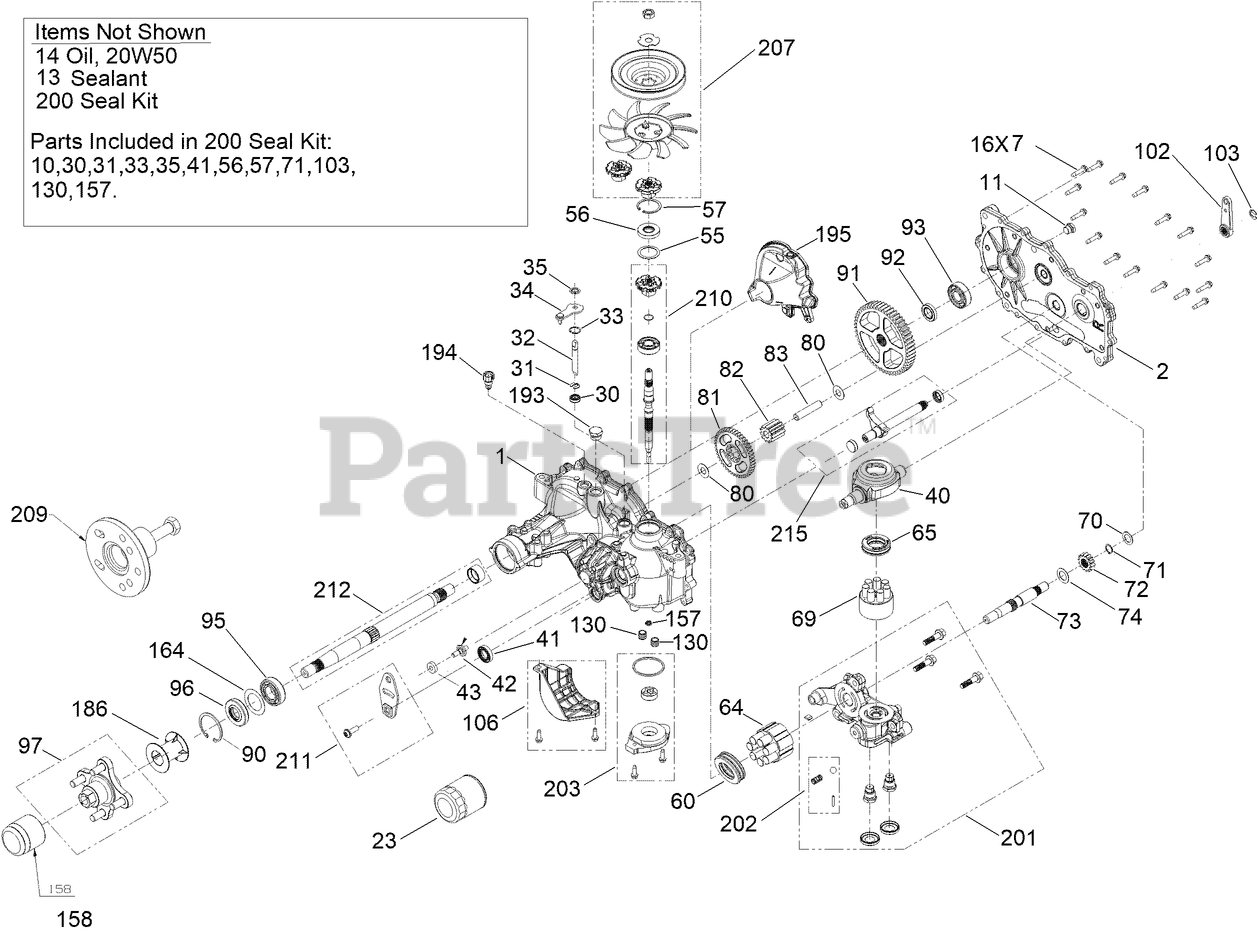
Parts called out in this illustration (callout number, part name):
1	RH MAIN HOUSING KIT
2	RH SIDE COVER KIT
7	SCREW-HHF
13	SEALANT
23	ELEMENT-OIL FILTER, HYD
30	SEAL-LIP
31	RING-RETAINING, EXTERNAL
32	ROD-BYPASS
33	RING-RETAINING, INTERNAL
35	RING-RETAINING, EXTERNAL
40	SWASHPLATE-TRUNNION
41	SEAL-LIP
43	PUCK-FRICTION
55	SPACER
57	RING-RETAINING
60	BEARING-THRUST
64	CYLINDER BLOCK ASM KIT
65	BEARING-THRUST
69	PUMP BLOCK ASM
70	WASHER-FLAT
71	RING-RETAINING
72	GEAR-14T
73	SHAFT-MOTOR
74	WASHER
80	WASHER
81	GEAR-45T
82	GEAR-11T
90	RING-RETAINING
91	GEAR-54T
92	SPACER
93	BEARING-BALL
95	BEARING-BALL
97	HUB-OFFSET
102	HANDLE-BRAKE
103	RING-RETAINING, EXT
106	FILTER GUARD KIT
130	TUBE-CHARGE
157	GEROTOR SEAL KIT
158	CAP-AXLE, LONG
164	SPACER
186	TUBE-AXLE
194	BREATHER FITTING ASM
195	RH INTERNAL EXPANSION TANK ASM
200	SEAL KIT
202	CHARGE RELIEF KIT
203	CHARGE KIT
207	FAN AND PULLEY KIT
210	INPUT SHAFT KIT
211	CONTROL ARM KIT
215	INBOARD KIT
